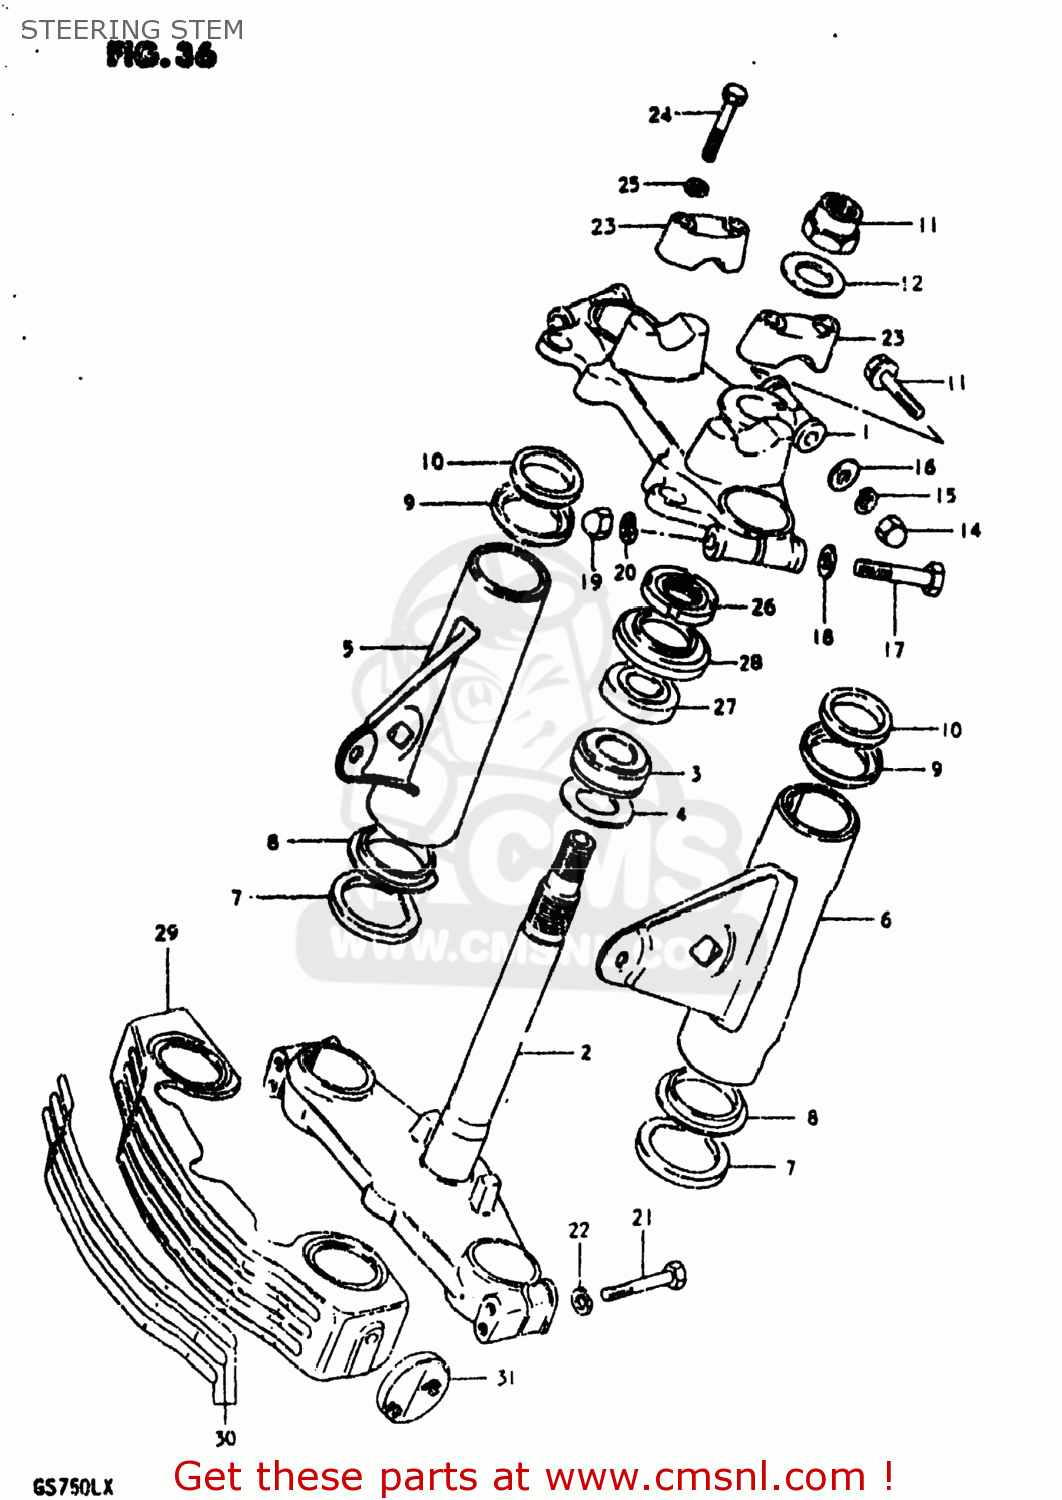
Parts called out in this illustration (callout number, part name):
1	HEAD,STEERING STEM
2	STEM,STEERING
3	BEARING
4	WASHER,THRUST
5	BRACKET,HEADLAMP,RIGHT
6	BRACKET,HEADLAMP,LEFT
7	SEAT.HEAD LAMP
8	CUSHION,HEADLAMP BRACKET
9	GUIDE
10	CUSHION,HEADLAMP BRACKET UPR
11	NUT,FR FORK UPR BRACKET
12	WASHER
13	BOLT
14	NUT,M8X1.25X12
15	LOCK WASHER
16	WASHER
17	BOLT 10X55
18	WASHER
19	NUT, LOWER LH
20	LOCK WASHER
21	BOLT 8X45
22	WASHER,LOCK,8.
23	HOLDER,HANDLE UPR
24	BOLT
25	LOCK WASHER
26	NUT,STEERING STEM(25X44X10)
27	TAPER,ROLLER BEARING
28	DUST SEAL,STEERING,UPPER
29	COVER,FRONT FORK
30	TAPE SET,FRONT FORK COVER
31	REFLEX REFLECTOR,RR
